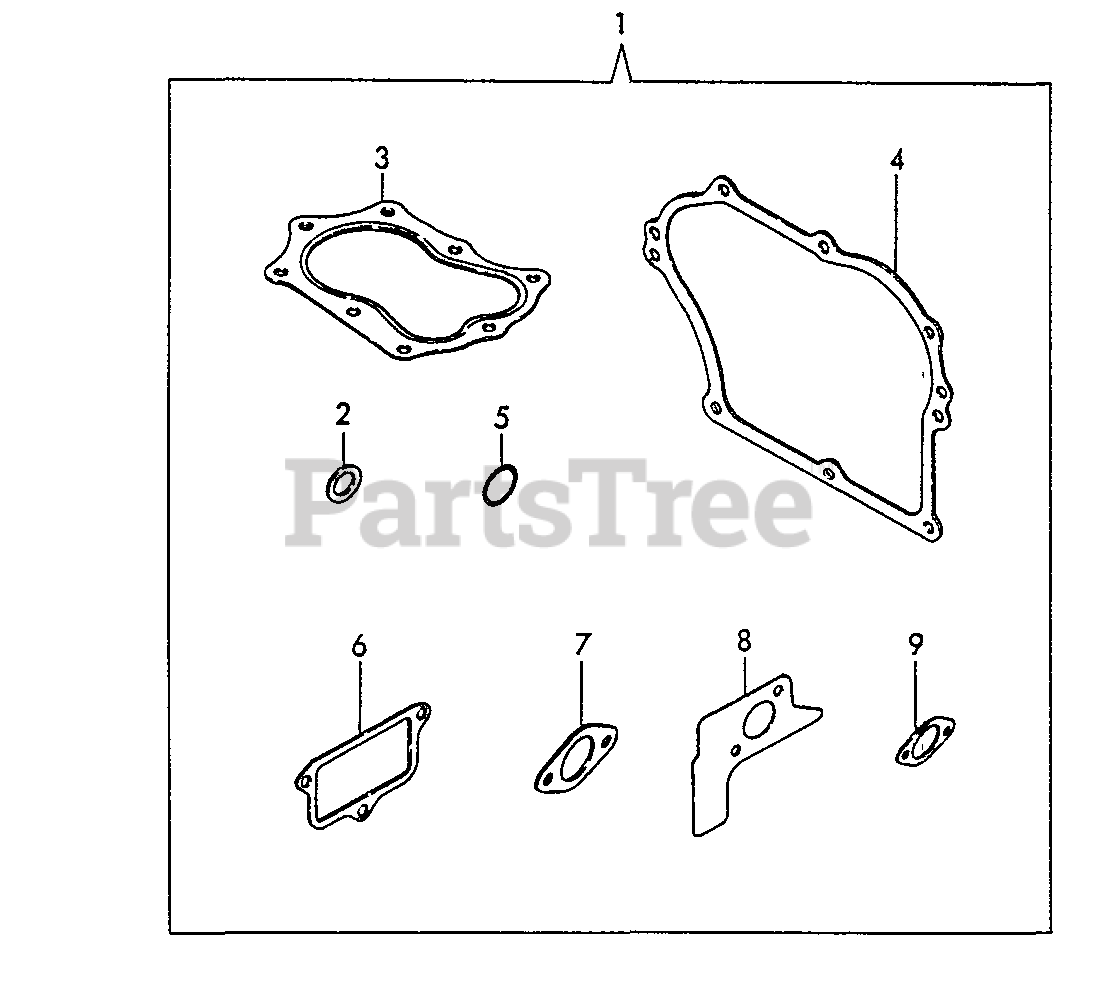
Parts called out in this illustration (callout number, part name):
1	GASKET KIT
2	GASKET
3	GASKET, CYLINDER
4	GASKET, SIDE COVER
5	O-RING - 18
6	GASKET
7	GASKET, INTAKE
8	GASKET, EXHAUST
9	GASKET, SPACER
